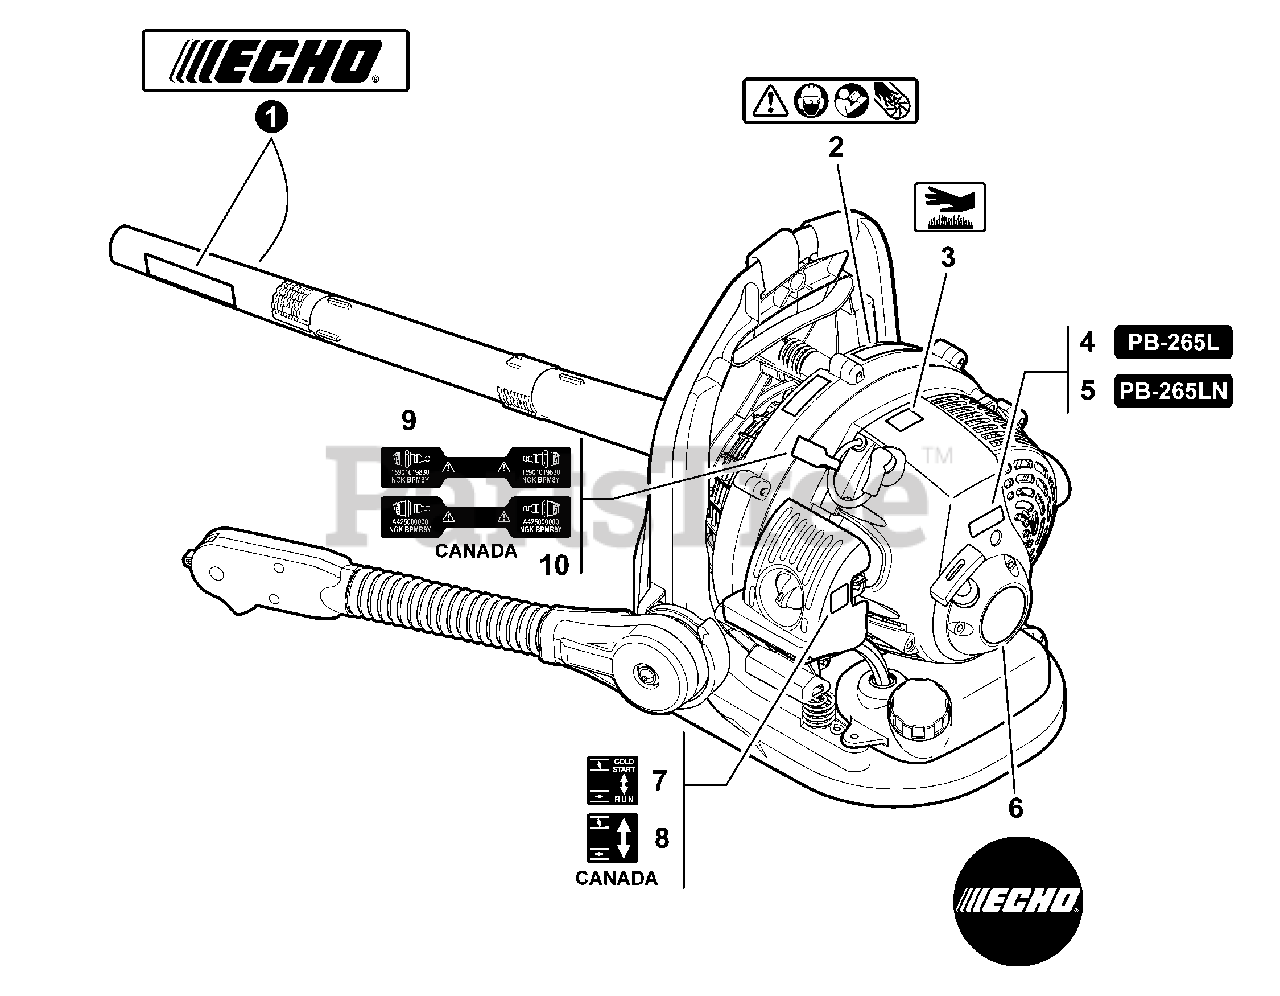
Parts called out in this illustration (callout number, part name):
1	LABEL, ECHO BLOWER TUBE
2	LABEL, CAUTION - ISO
3	LABEL, CAUTION - HOT
4	LABEL, MODEL
5	LABEL - MODEL PB-265LN
6	LABEL, RECOIL STARTER
7	LABEL, CHOKE
8	LABEL, CHOKE
9	LABEL, SPARK PLUG - BPM8Y
10	LABEL, SPARK PLUG - BPMR8Y
